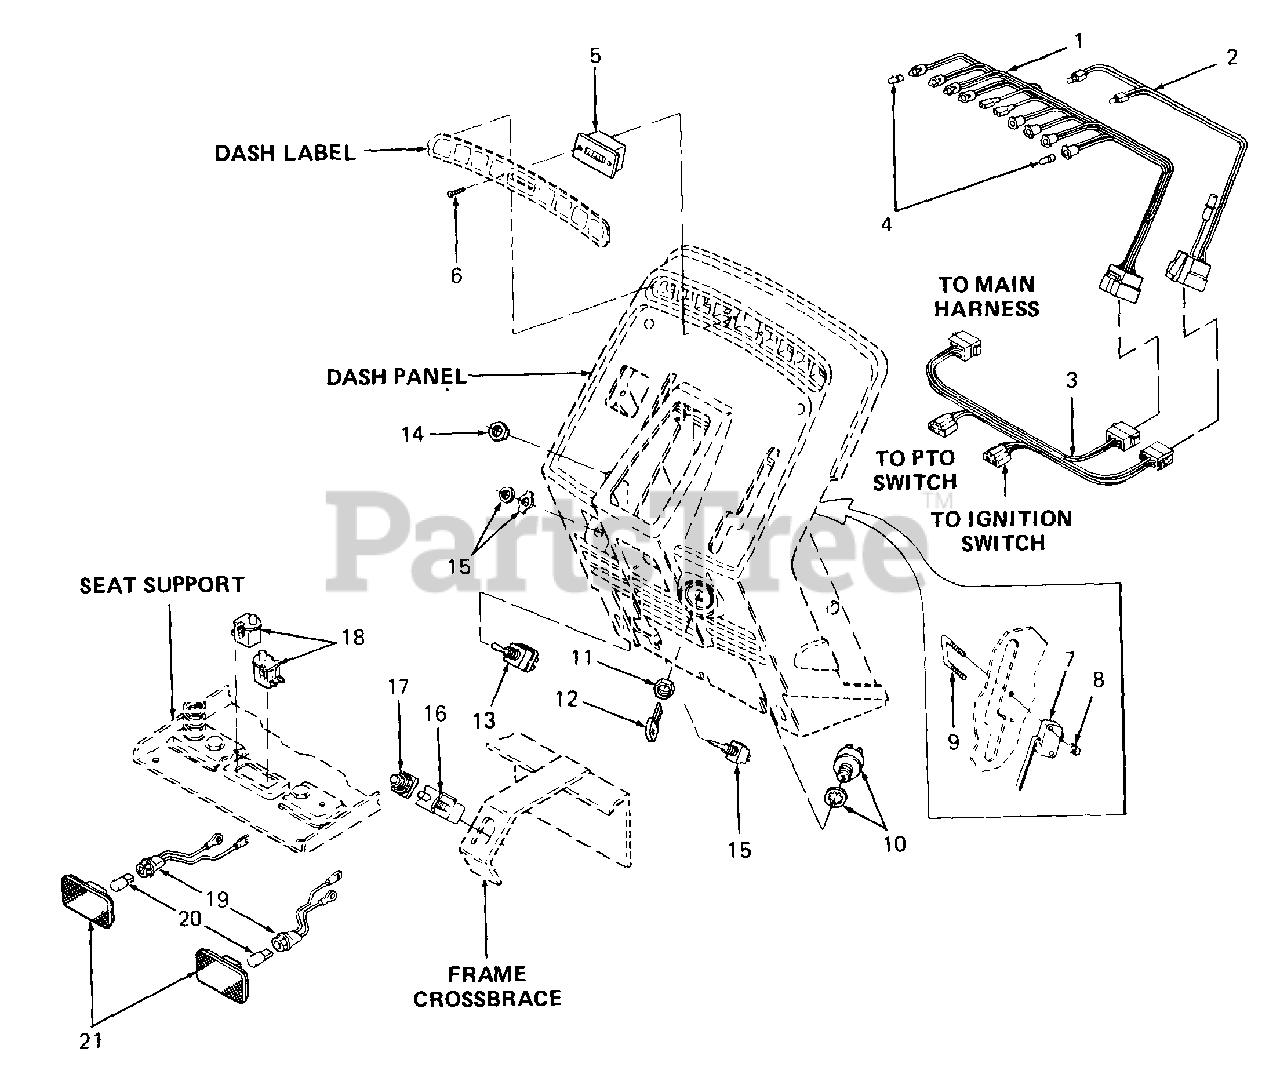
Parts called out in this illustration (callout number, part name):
1	Harness, Indicator Wire
2	Harness, Indicator Adapter
3	Harness, Pedestal
4	Bulb, Indicator
5	Hour Meter
6	Screw, Truss Hd Tapp, #6 X .62 Lg
7	Switch, Reverse
8	Nut, Hex Insert Lock, #4-40
9	Screw, Switch
10	Switch, Ignition
11	Nut, Ignition Switch
12	Key, Ignition
13	Switch, PTO
14	Nut, Hex, 1/2-27 X .100 Thk
15	Switch, Headlight
16	Switch, Interlock
17	Boot, Switch
18	Switch, Snap Mount Normally Open
19	Cable Assy, Tail Light
20	Bulb, Tail Light
21	Lens Assy, Tail Light
